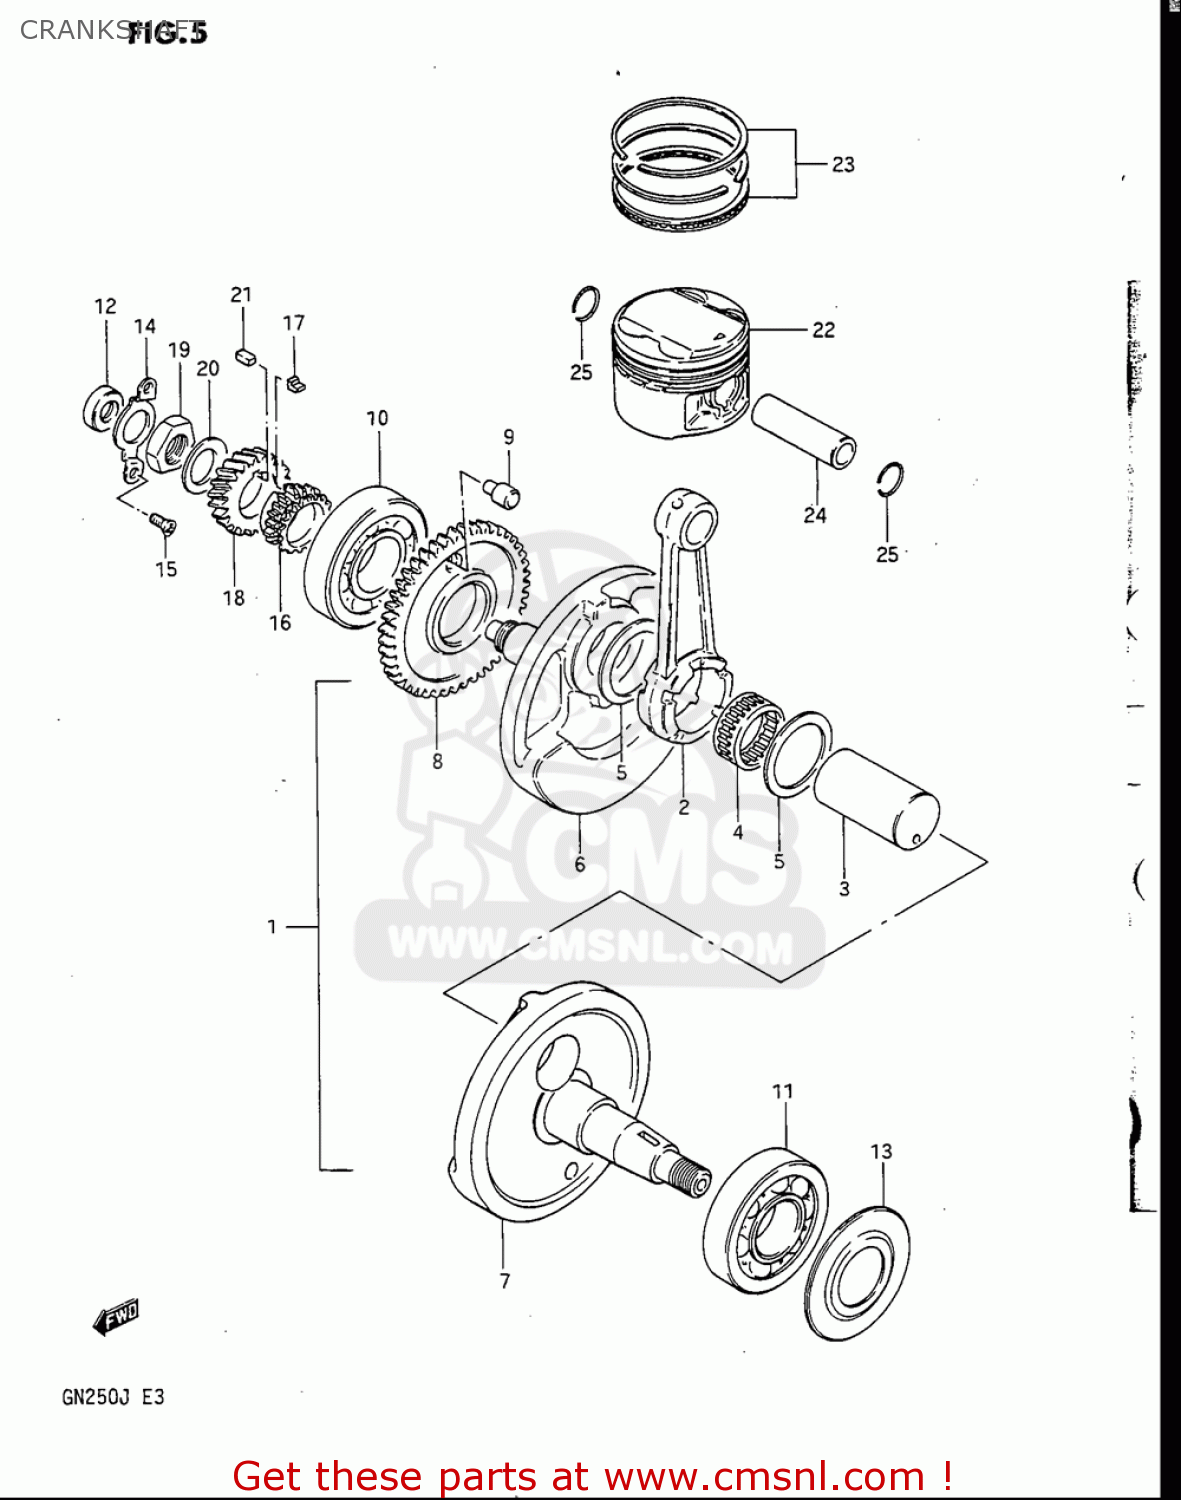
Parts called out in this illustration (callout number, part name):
1	CRANKSHAFT ASSEMBLY
2	ROD,CONNECTING
3	PIN,CRANK
4	BEARING(31X39X21)
5	WASHER(31X48.5X1)
6	CRANKSHAFT,R
9	PIN
10	BEARING(30X72X19)
11	BEARING(35X80X21)
12	SEAL,OIL(14X26X6)
13	WASHER,CRANKSHAFT OIL SEALING
14	RETAINER,CRANKSHAFT BEARING,R
15	SCREW(5X10)
16	SPROCKET,CAM CHAIN DRIVE(NT:21
17	KEY,SPROCKET
19	NUT
20	WASHER
21	KEY
22	PISTON
23	RING SET,PISTON
24	PIN,PISTON
25	CIRCLIP,PISTON PIN
